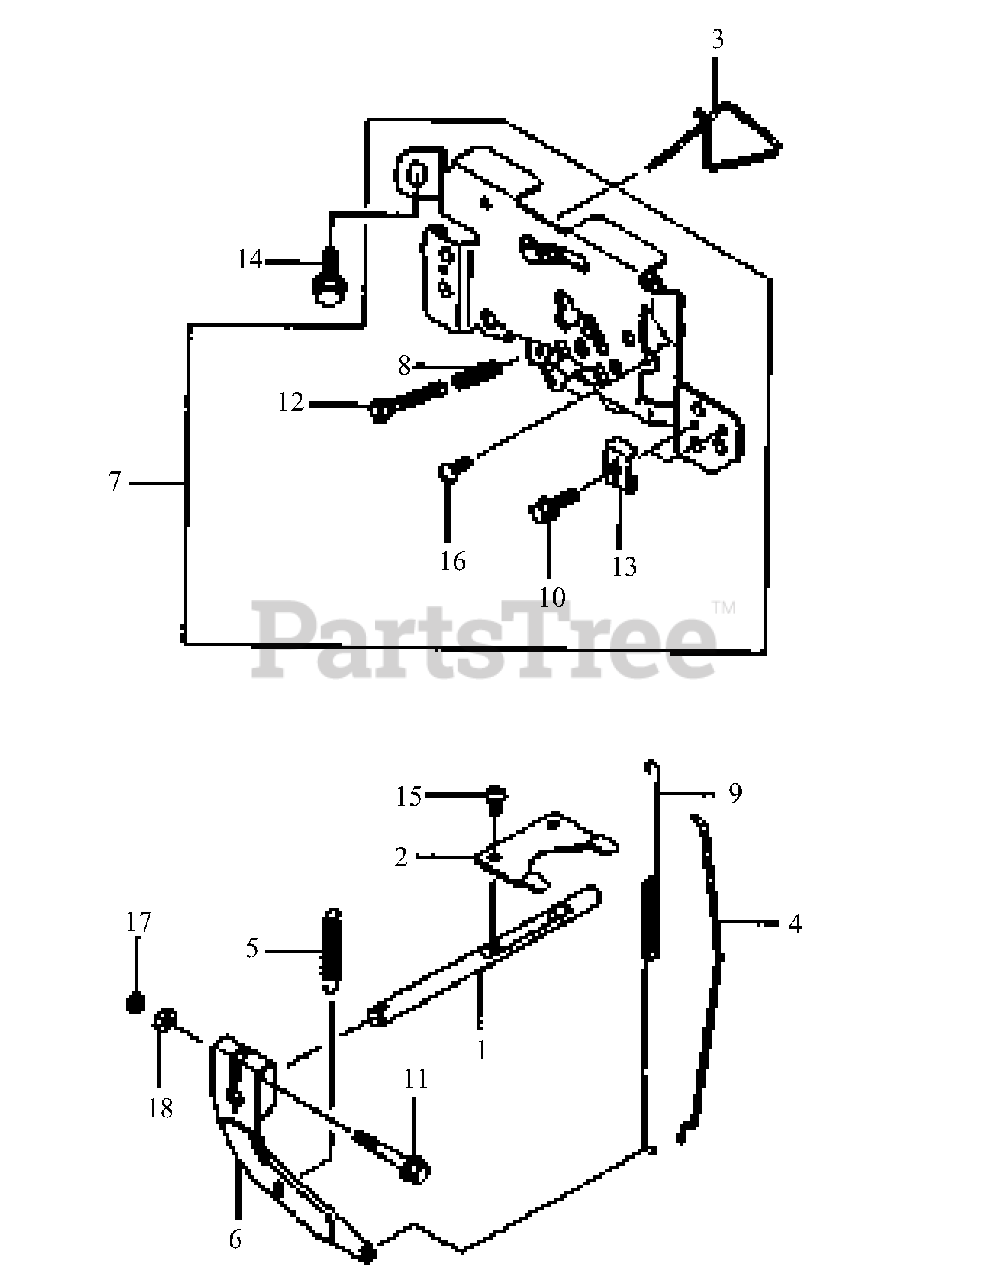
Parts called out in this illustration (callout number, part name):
3	Link-Choke
4	Link
5	Spring-Governor
6	Arm-Governor
7	Panel-Comp-Control
10	Bolt, 5 x 18 mm
11	Bolt, 6 x 30mm
12	Bolt 5 x 30 mm
18	Washer-Plain
